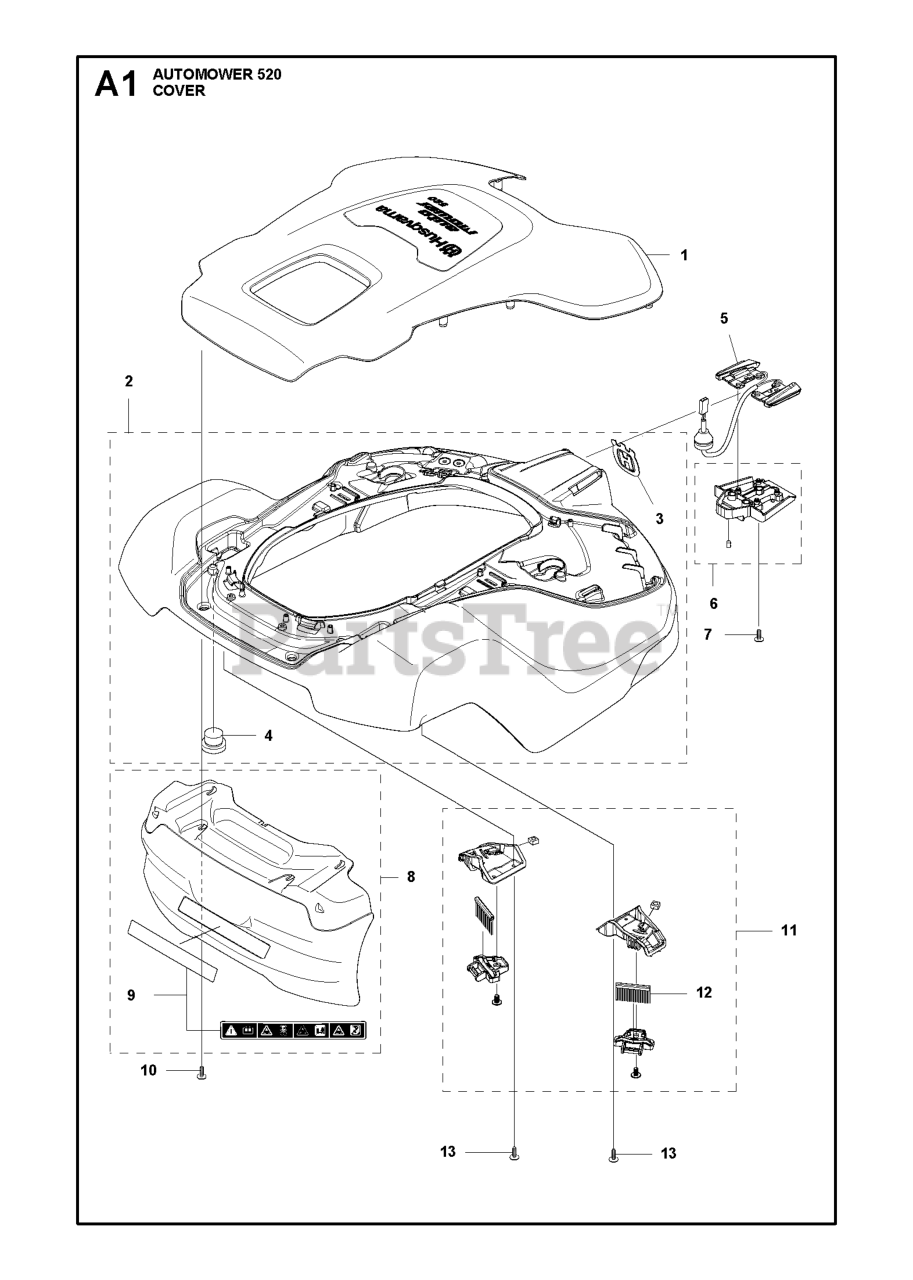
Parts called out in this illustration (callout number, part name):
2	BODY ASSY
3	DECAL HUSQVARNA CROWN HEIGHT 5
4	CAP SNAPLOC
5	CABLE ASSY CHARGING PLATE
6	HOLDER ASSY MAGNET
7	SCREW 14MM
8	BUMPER ASSY
9	LABEL WARNING P15
10	SCREW ITXPANT
11	BRUSH KIT 430/450
12	WHEEL BRUSH REFILL KIT
13	SCREW 14MM
